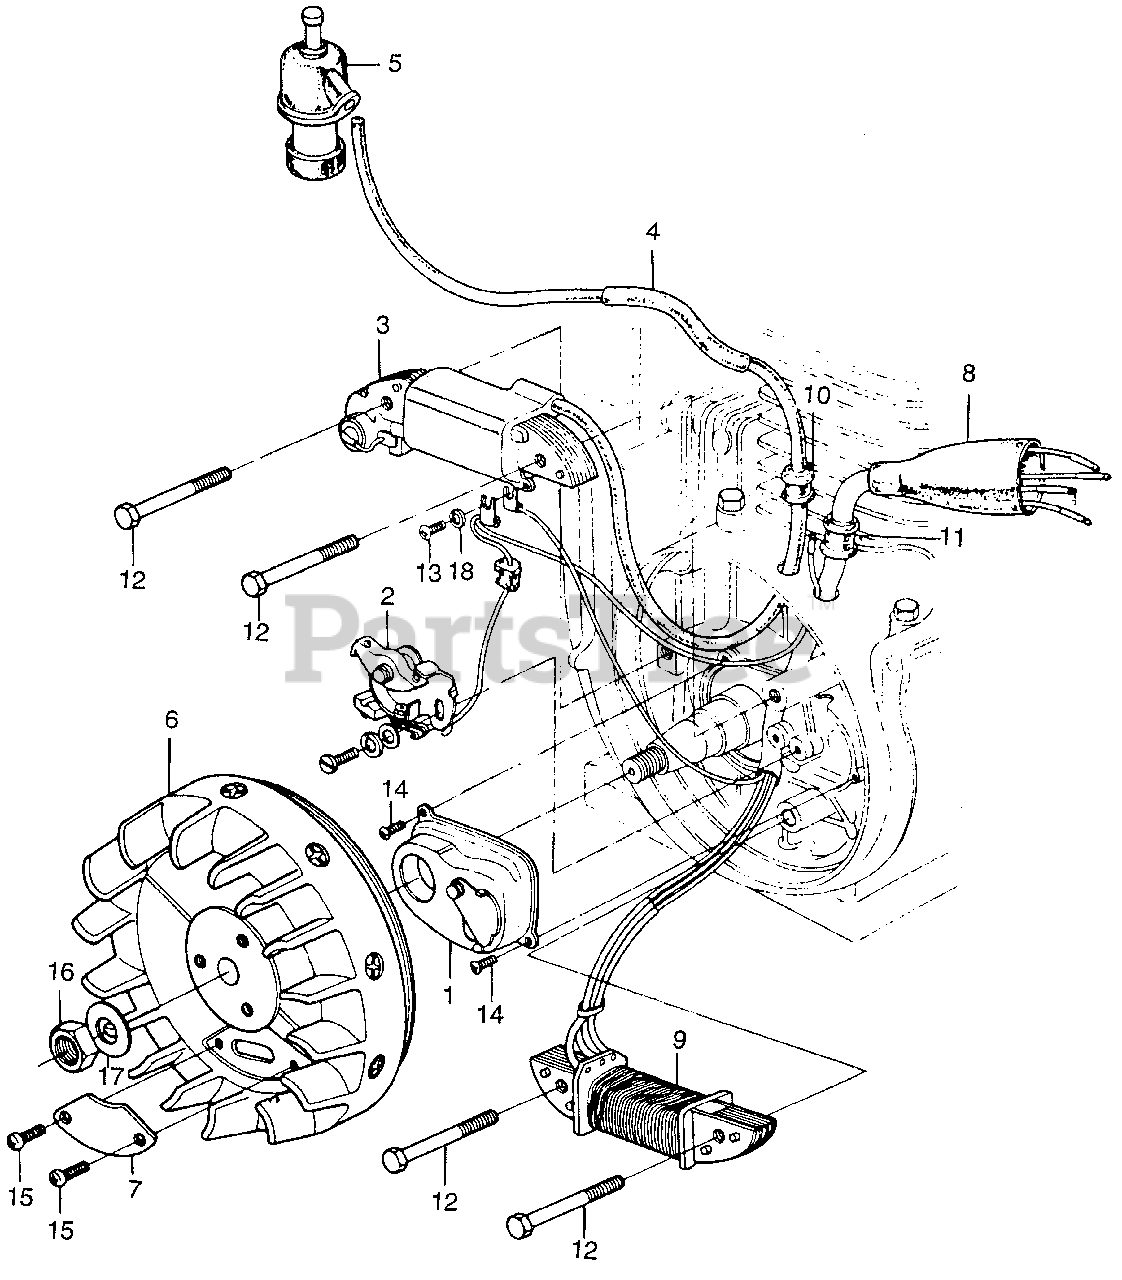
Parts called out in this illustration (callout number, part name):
1	COVER, POINT
2	POINTS ASSY. (NOT AVAILABLE)
3	COIL, IGNITION (KOKUSAN)
4	TUBE, IGNITION RUBBER (NOT AVAILABLE)
5	CAP ASSY., NOISE SUPPRESSOR
6	MAGNETO, FLYWHEEL (KOKUSAN) (NOT AVAILABLE)
7	COVER, FLYWHEEL WINDOW (NOT AVAILABLE)
10	GROMMET, WIRE
12	BOLT, HEX. (6X28)
14	SCREW, PAN (5X6)
15	SCREW, PAN (5X8)
16	NUT, HEX. (14MM)
17	WASHER (14MM) (NOT AVAILABLE)
